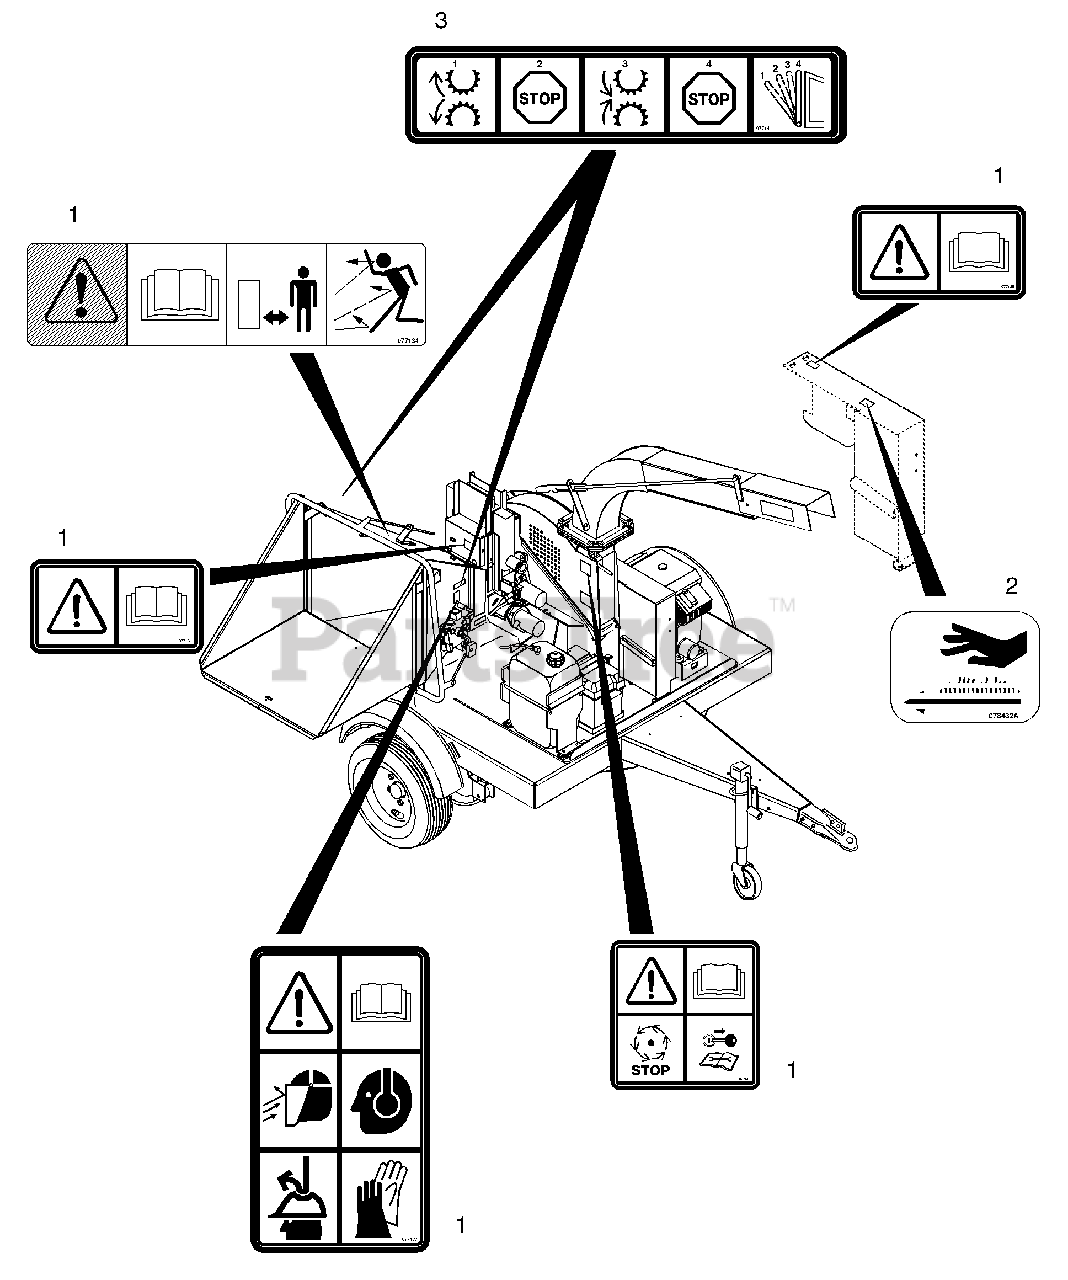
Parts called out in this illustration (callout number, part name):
1	Decal Set - Chipper CE
2	Decal- Hot Surface
3	Decal Set - Chipper BLK/WHT
